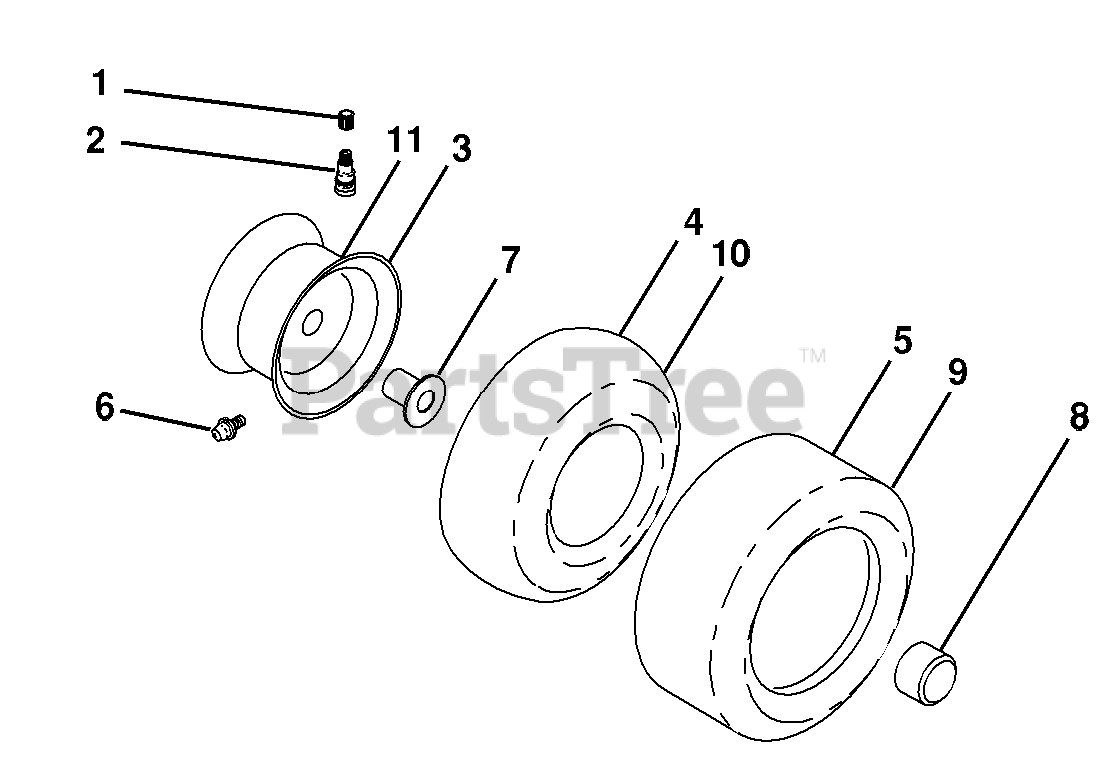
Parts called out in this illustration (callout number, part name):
2	VALVE STEM LT
3	RIM ASM 6" FRONT SILVER
4	TUBE.5.3/4.5/6
5	TIRE HEAVY DUTY
6	FITTING LT
7	BEARING T
8	CAP, AXLE BLK
9	TIRE.TS.20X10-8
10	TUBE
11	RIM ASM 8" REAR SILVER
